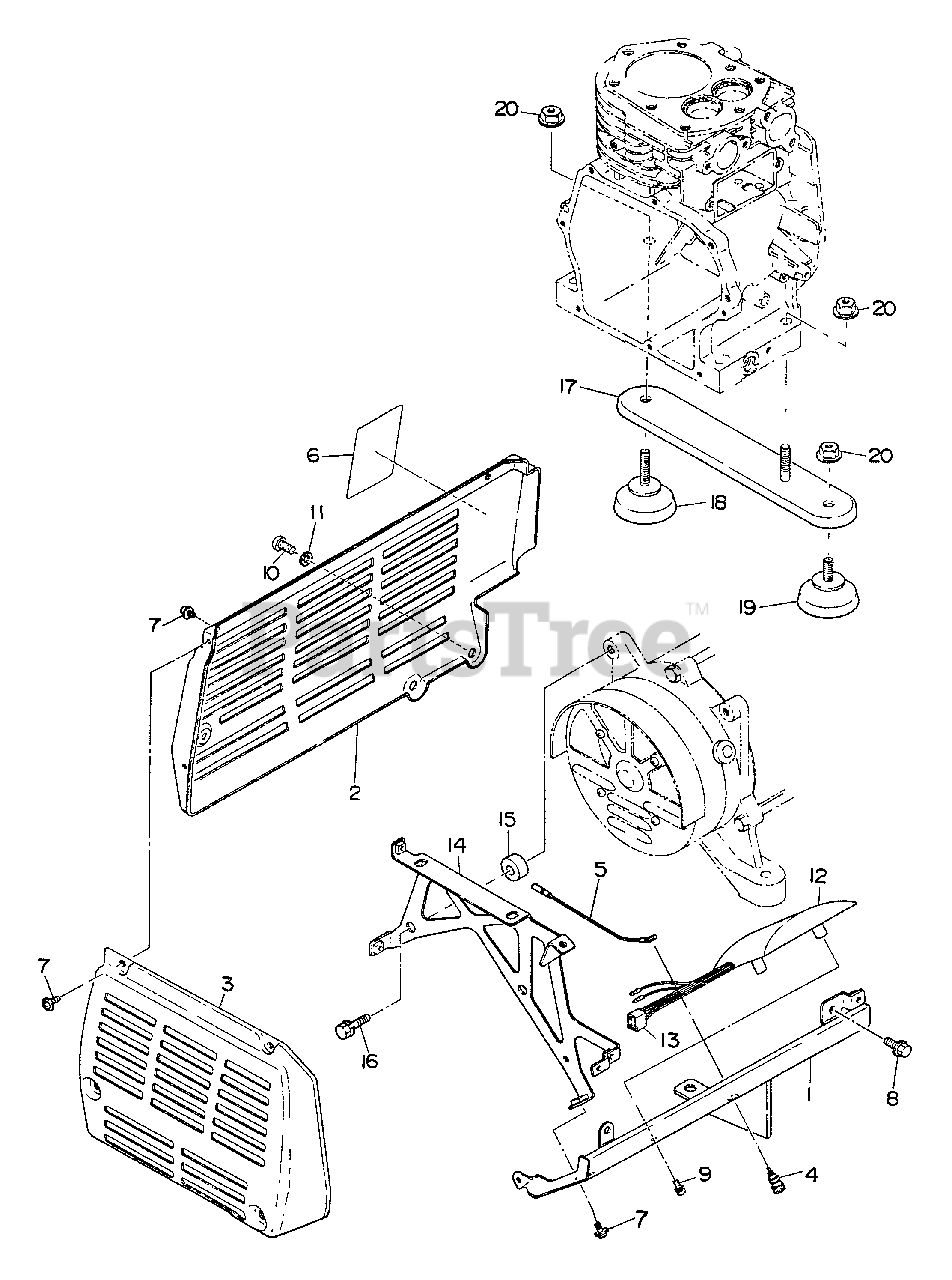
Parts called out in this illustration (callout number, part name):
1	FRONT COVER ASSY
2	COVER ASSY - REAR
3	SIDE COVER
4	BOLT, TERMINAL - BLACK
5	LEAD - GROUND
6	LABEL - SPECIFICATION
7	SCREW
8	SCREW
9	SCREW
10	SCREW
11	WASHER
12	AVR ASSY
13	CONNECTOR
14	MOUNT ASSY
15	SPACER
16	BOLT
17	MOUNT ASSY
18	MOUNT ASSY
19	MOUNT ASSY
20	NUT - 8 -- FLANGE
